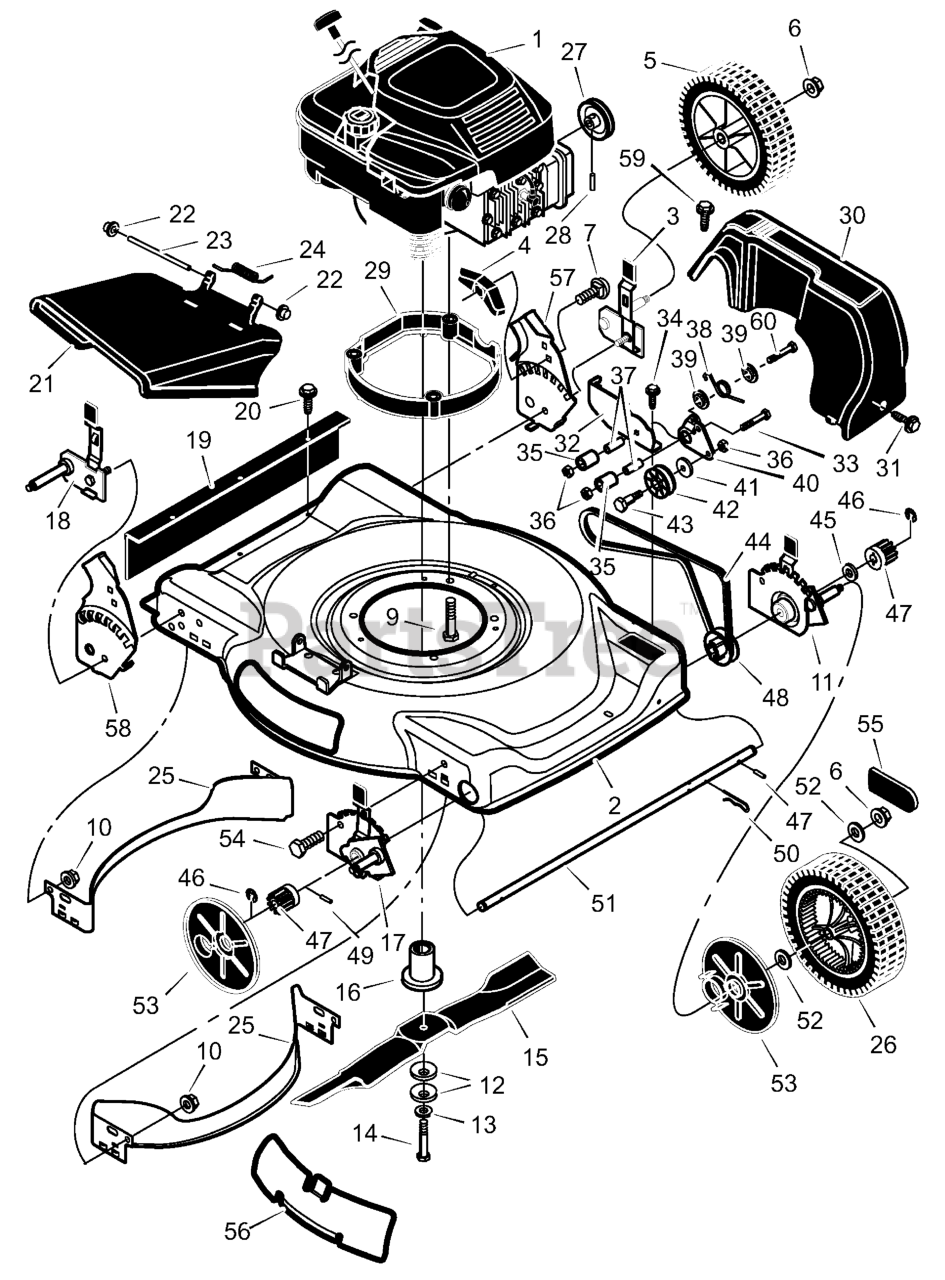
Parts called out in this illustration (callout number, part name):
1	Engine *
2	Housing
3	Height Adjuster, Left Rear
5	Wheel and Tire, Rear
6	Locknut, Flange
7	Bolt, Carriage
9	Bolt, Engine
10	Nut
11	Height Adjuster, Left Front
12	Washer, Belleville
14	Bolt, Hex
15	Blade, Mulcher
16	Adapter, Blade
17	Height Adjuster, Right Frt.
18	Height Adjuster, Right Rr.
19	Guard, Rear
21	Deflector, Chute
22	Push-On Cap
23	Pin, Pivot
26	Wheel and Tire, Drive
28	Pin, Spring
29	Base, Engine
30	Cover, Belt (Black)
32	Bracket, Idler Support
35	Idler, Backside
36	Locknut
37	Bearing
40	Arm, Pivot
42	Pulley, Idler
43	Bolt, Shoulder
44	Belt, Tecumseh
46	Ring, Retainer
47	Gear, Pinion
49	Pin, Drive
50	Pin, Hair
52	Washer
53	Cover, Dust
54	Bolt
55	Hub Cap
56	Plate, Mulcher
57	Bracket, Left Handle
58	Bracket, Right Handle
